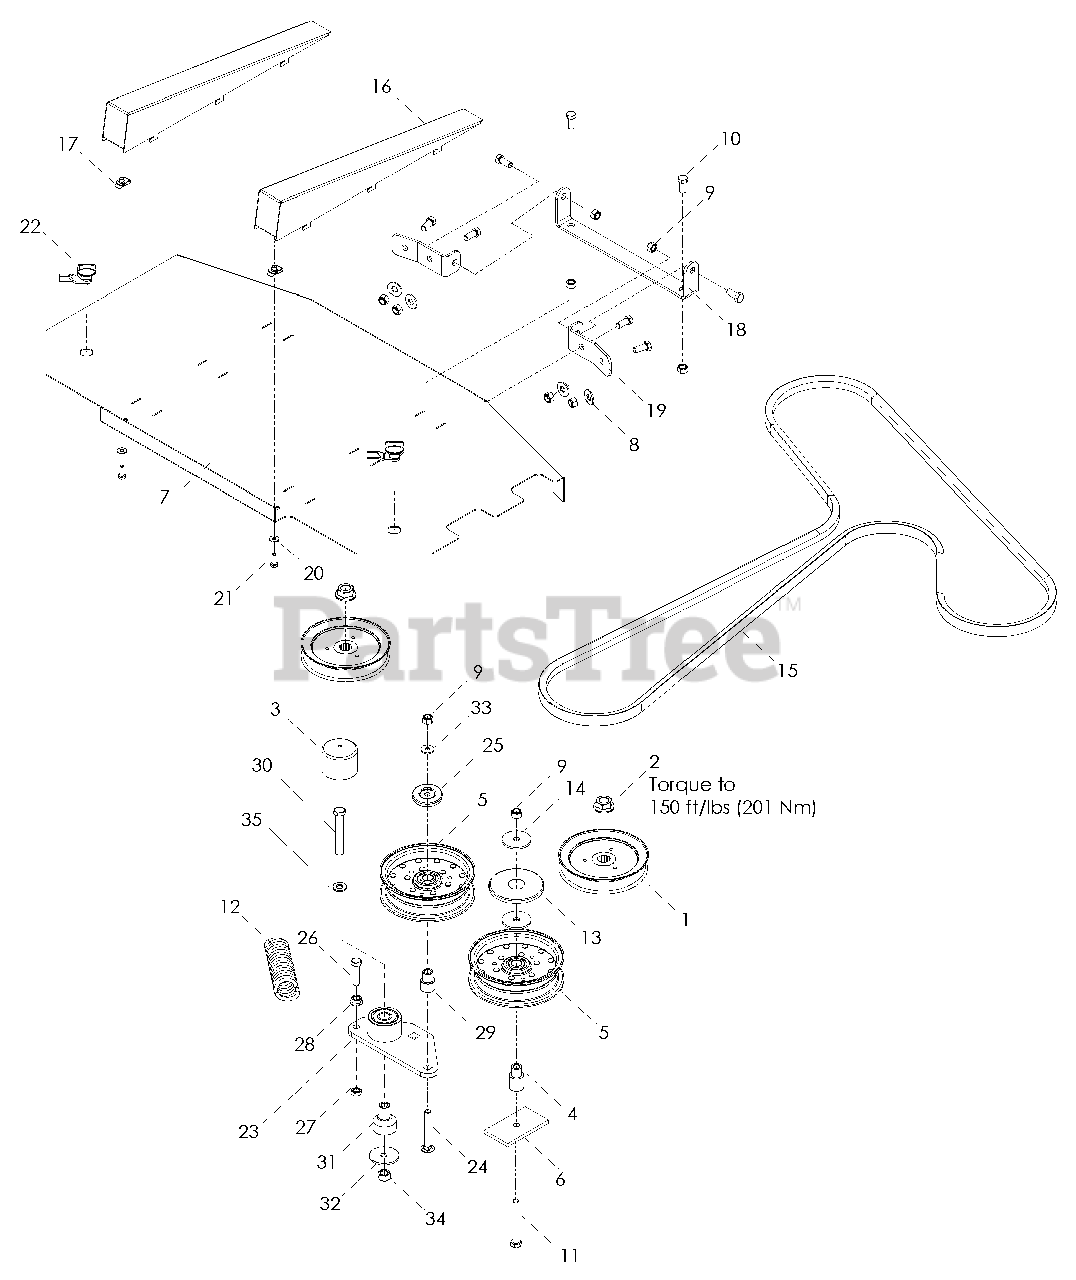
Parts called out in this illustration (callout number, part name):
2	NUT 3/4-16 FLANGE
3	CAP, VINYL
4	BUSHING, IDLER
5	PULLEY, IDLER
6	PAD, PAINTED
7	COVER, BELT, 36
8	WASHER 3/8 FLAT
9	NUT 3/8-16 HEX NYLOC
10	HCS 3/8-16 x 7/8
11	HCS 3/8-16 x 3
13	DUST CAP, TOP
14	WASHER, 3/8 SPECIAL
15	BELT, DECK 36
17	RETAINER 1/4-20 "U" TYPE
18	HINGE, BIN
19	BASE, HINGE
20	WASHER, 1/4 FLAT SAE
21	HCS 1/4-20 x 3/4
22	LATCH, SHORT WING
23	ARM, IDLER, W/BEARINGS
24	RHSNB 3/8-16 x 2 3/4
25	SHIELD, DUST
26	HCS 3/8-16 x 1 1/2 GR 8
27	NUT 3/8-16 HEX JAM
28	NUT 3/8-16 HEX WHIZLK
29	BUSHING, IDLER
30	HCS 1/2-13 x 3 1/4
31	PIVOT, BEARING
32	WASHER, SUPPORT
33	WASHER, THICK 3/8
34	NUT 1/2 HEX NYLOC
35	WASHER, BELLEVILLE 1/2
